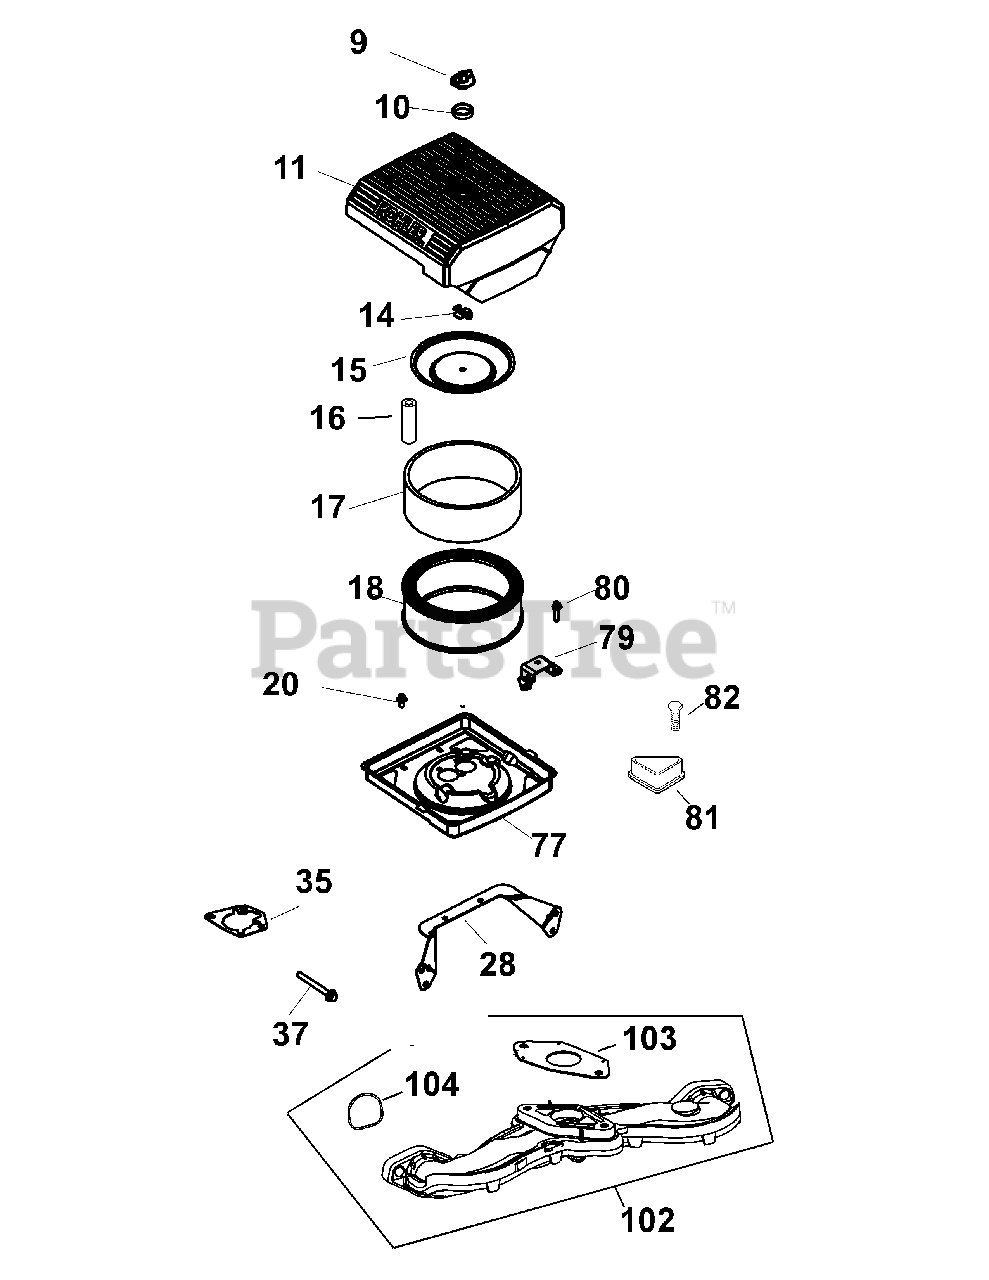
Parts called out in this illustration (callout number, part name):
15	Cover, Inner Air Cleaner
16	Seal, Inner Air Cleaner
17	Element, Precleaner (Low)
18	Element, Precleaner & Air Filter
20	Screw, Thread Forming
28	Bracket, Air Cleaner Base
35	Gasket, Air Cleaner Base
37	Screw, Flg M6X1.0X40
77	Kit, Air Cleaner Base
79	Bracket, Air Cleaner
80	Screw, Flg Thd Frm M6X1.0X16
81	Cover, Blwr Housing
82	Screw, Hex Washer Hi-Lo
102	Kit, Intake Manifold
103	Gasket, Carburetor
104	O-Ring, Intake Port
